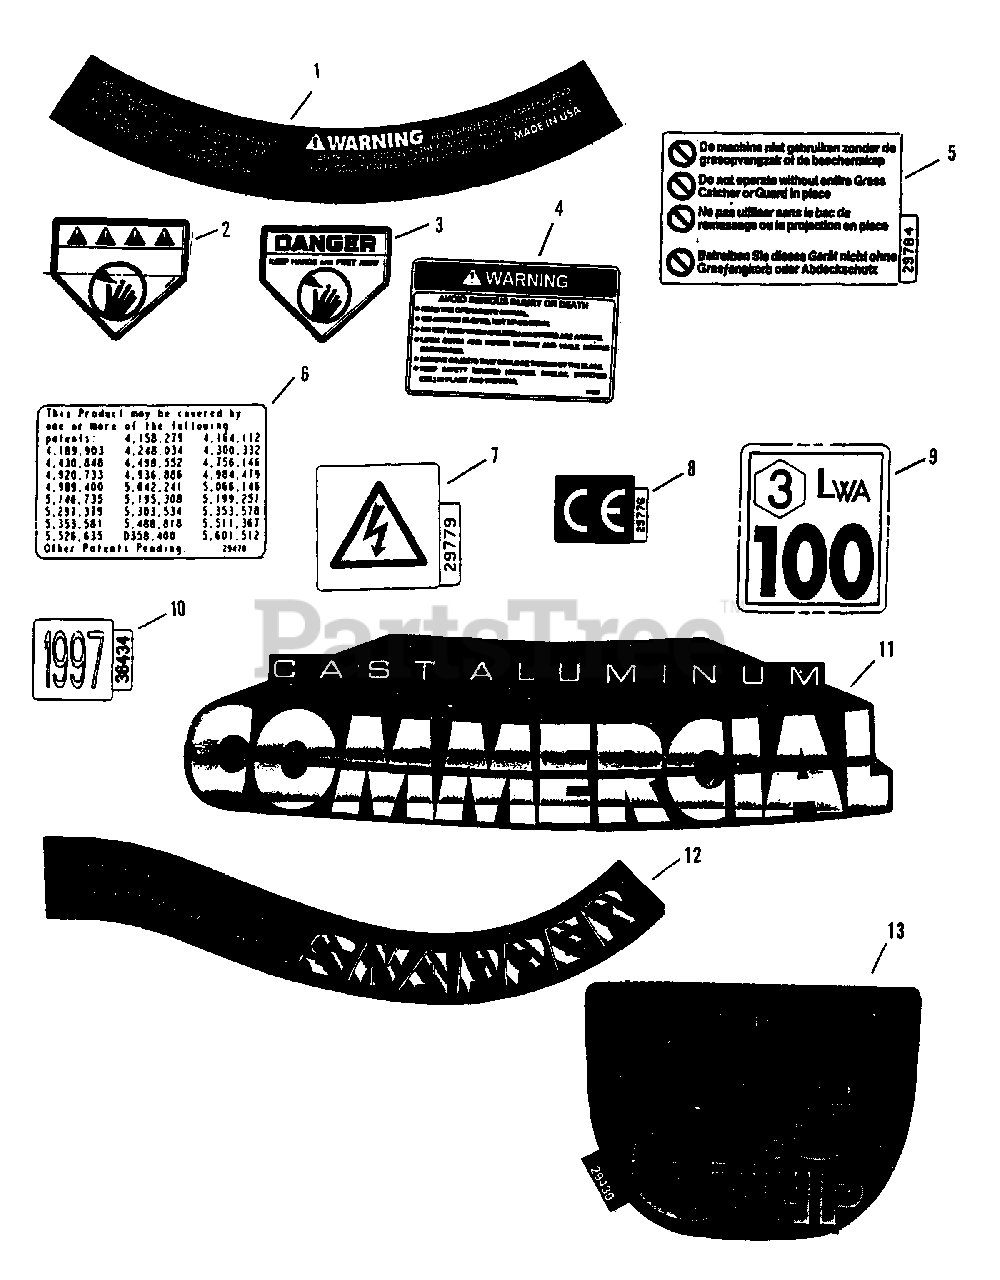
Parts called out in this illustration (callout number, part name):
1	DECAL - WARNING (Deck)
2	DECAL - WARNING (Deck)
3	DECAL - DANGER
4	DECAL, Warning
5	DECAL - DANGER
6	DECAL, Patent Numbers
7	DECAL, Spark Plug
8	DECAL, European Community
9	DECAL, Noise Control
10	DECAL, 1997 Year of Manufacture
11	DECAL, Deck
12	DECAL, Deck
13	DECAL, 6.5 Engine
